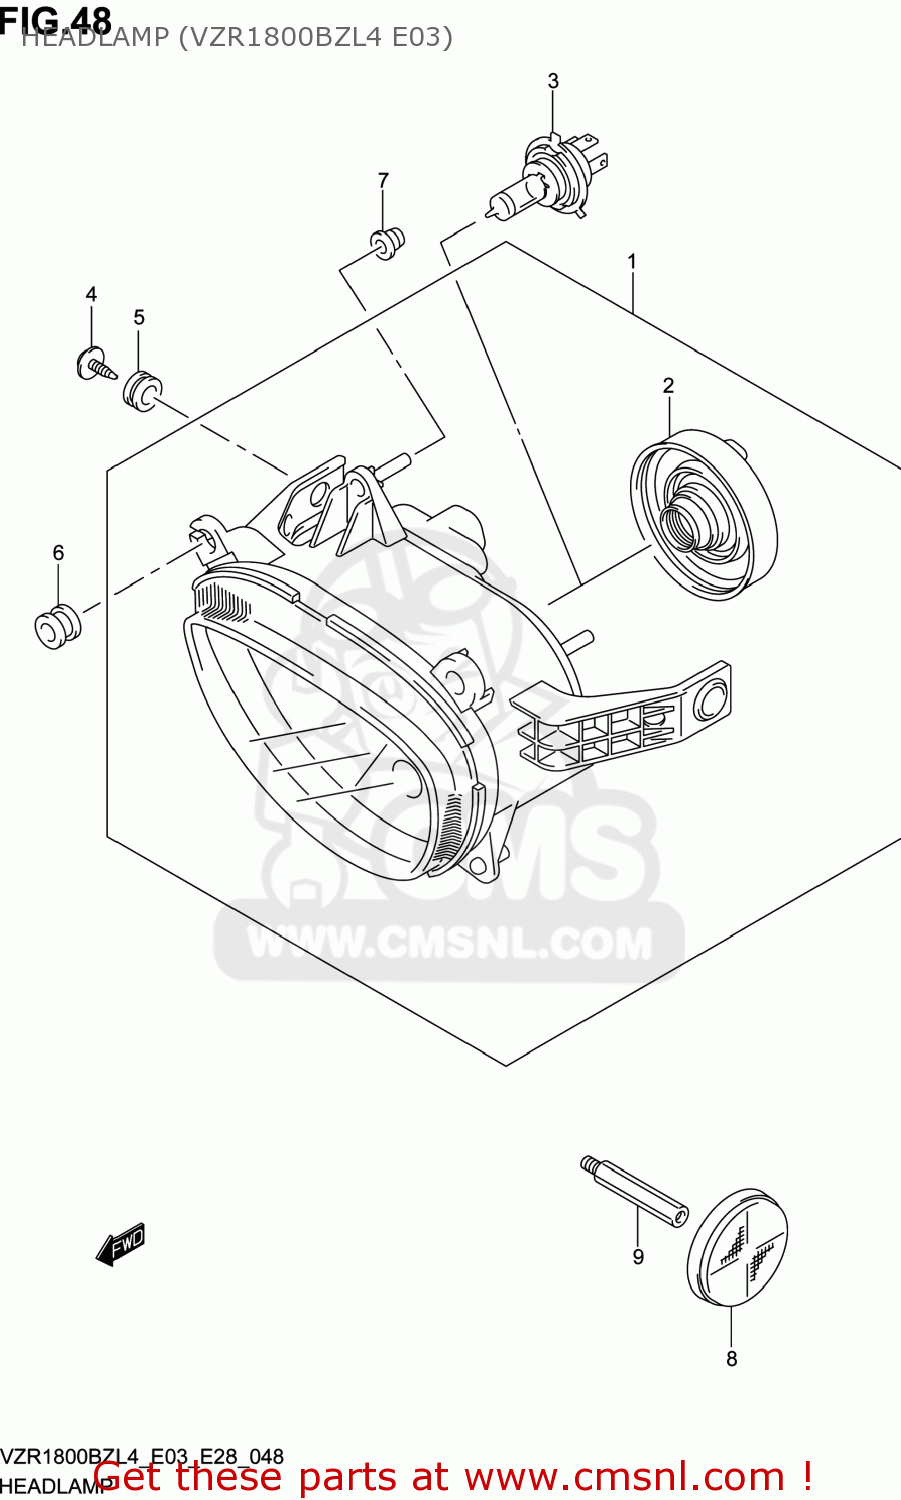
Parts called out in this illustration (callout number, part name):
1	HEADLAMP ASSY
2	COVER
3	BULB(12V60/55W,H4)
4	SCREW(5X15)
5	CUSHION
6	CUSHION
7	CUSHION
8	REFLEX REFLECTOR ASSY,FR SIDE
9	BOLT
